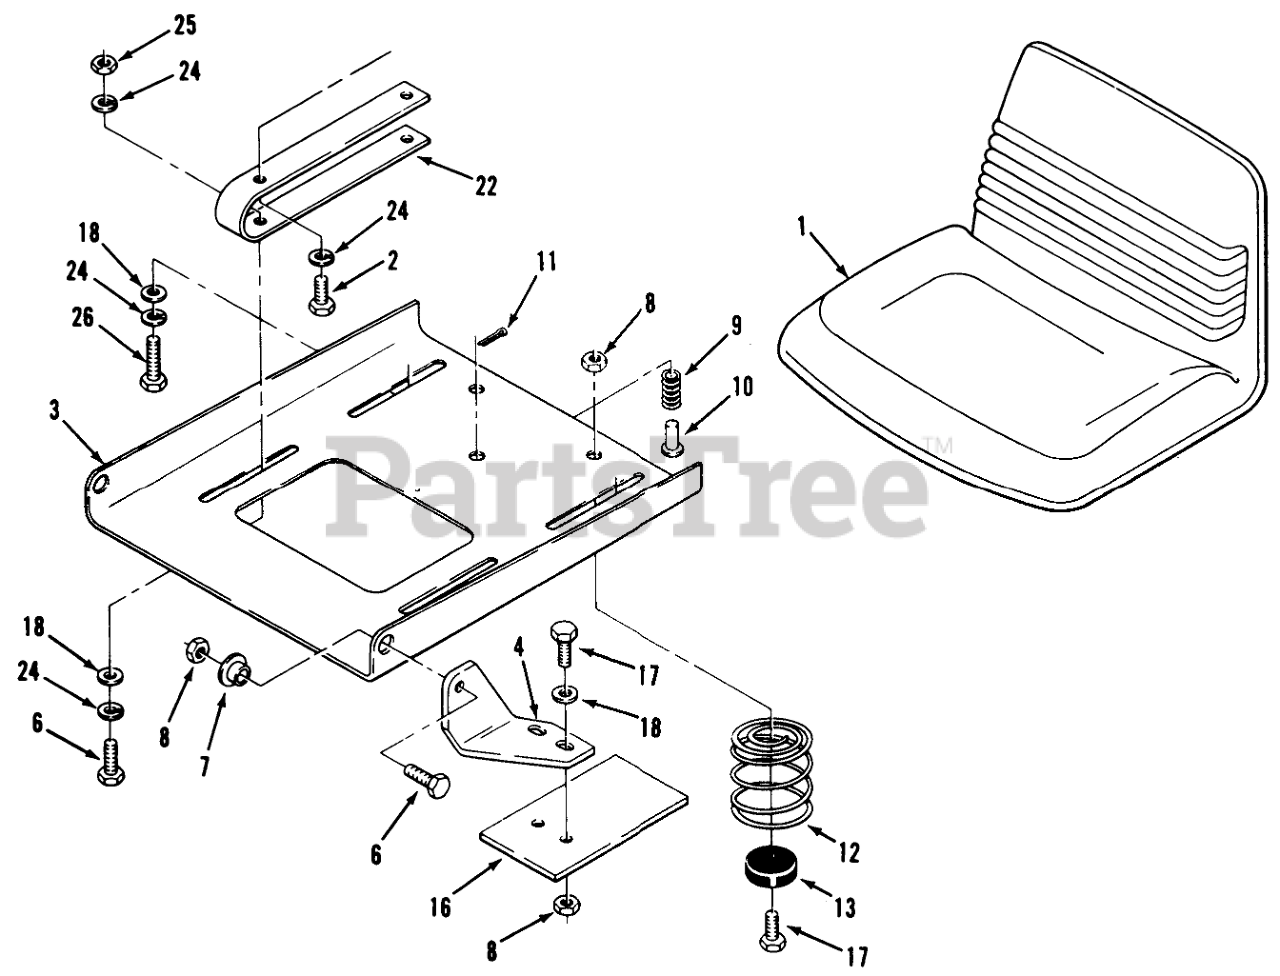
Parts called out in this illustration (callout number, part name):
1	Seat
2	SCREW-HH
3	PLATE-SEAT PIVOT B
4	BRACKET-PIVOT L.H B
6	SCREW-HH
7	BUSHING
8	NUT-LOCK, NI
9	SPRING-SEAT SWITCH
11	PIN-COTTER
12	Spring-Lifter
13	BUMPER
16	PLATE R
17	SCREW-HH
18	WASHER-PLAIN
22	SPRING-SEAT B
24	WASHER-LOCK
25	NUT-HEX
26	SCREW-HH
